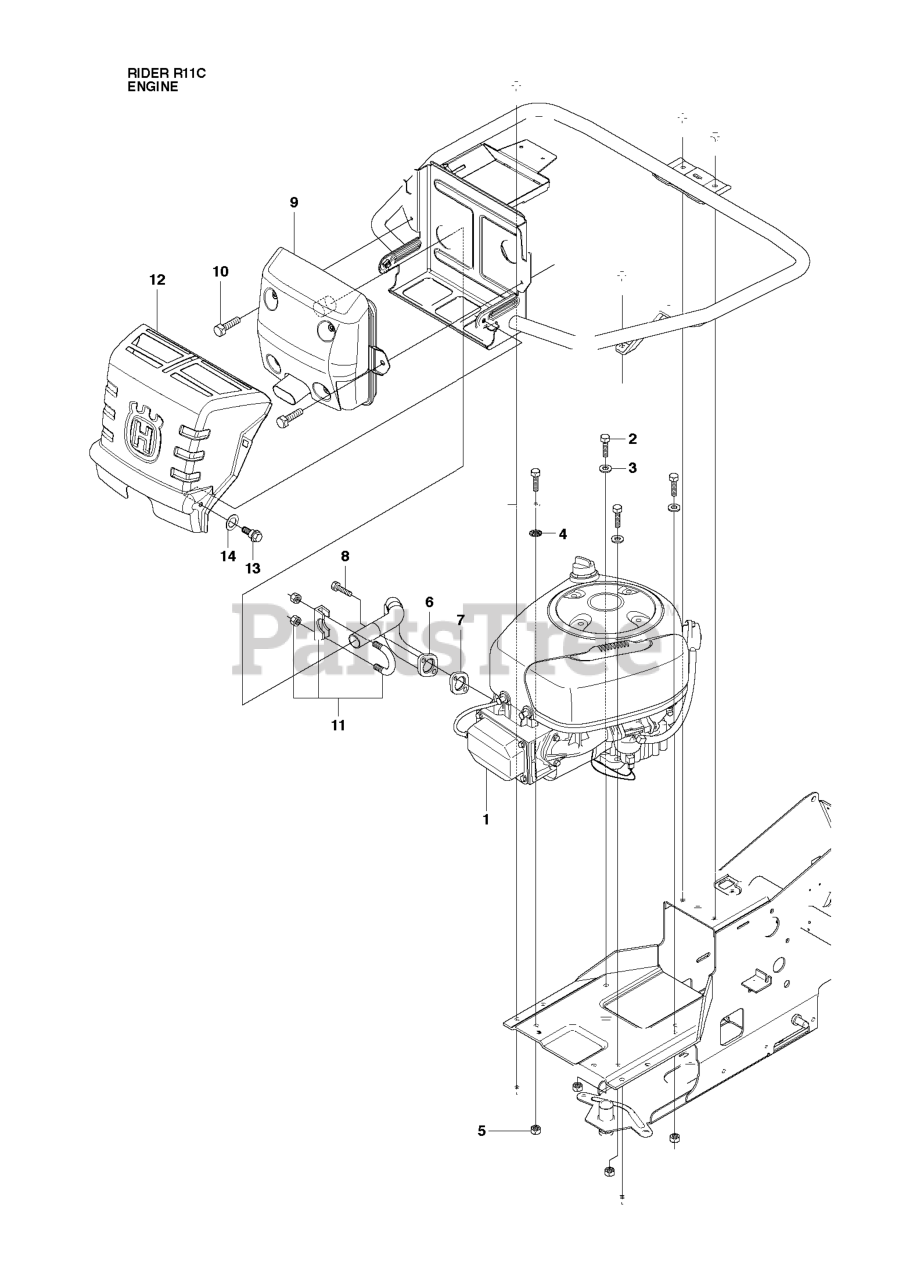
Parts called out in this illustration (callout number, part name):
3	WASHER BRB 8.4X17
5	LOCKNUT M8
6	EXHAUST PIPE ASSY
9	MUFFLER ASSY
11	CLAMP
12	HEAT PROTECTOR
14	SPRINGWASHER
